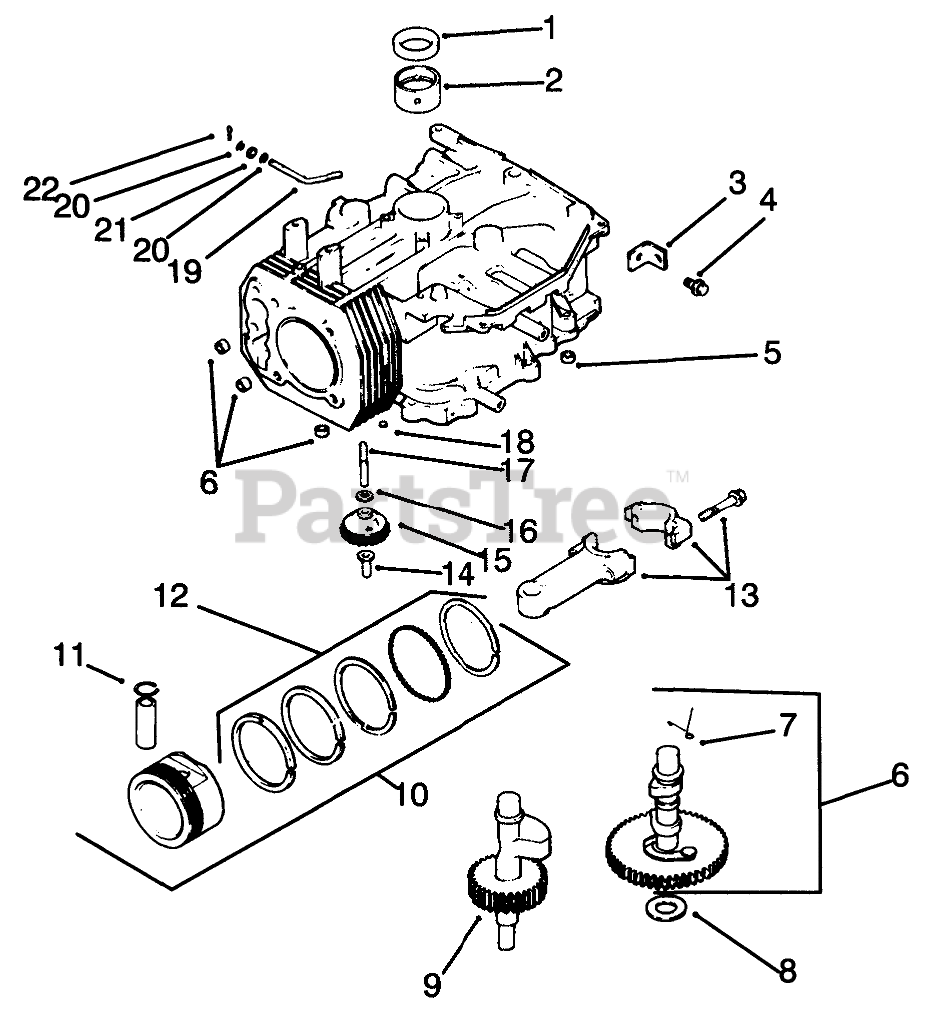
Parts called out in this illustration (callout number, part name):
1	Seal-Oil
2	Bearing-Crankshaft
3	Strap-Liting
5	Pin-Dowel
6	Camshaft Assembly
7	Spring-Actuating
8	Shim-Camshaft
9	Shaft-Balance
10	Piston W/Ring Set (Std.)
11	Retainer-Piston Pin
12	Ring Set (Std.)
13	Connecting Rod STD
14	Pin-Governor
15	Gear-Governor ASM
17	Shaft-Govenor Gear
18	Plug-Cap
19	Rod-Push
21	Seal
22	Pin-Hitch
